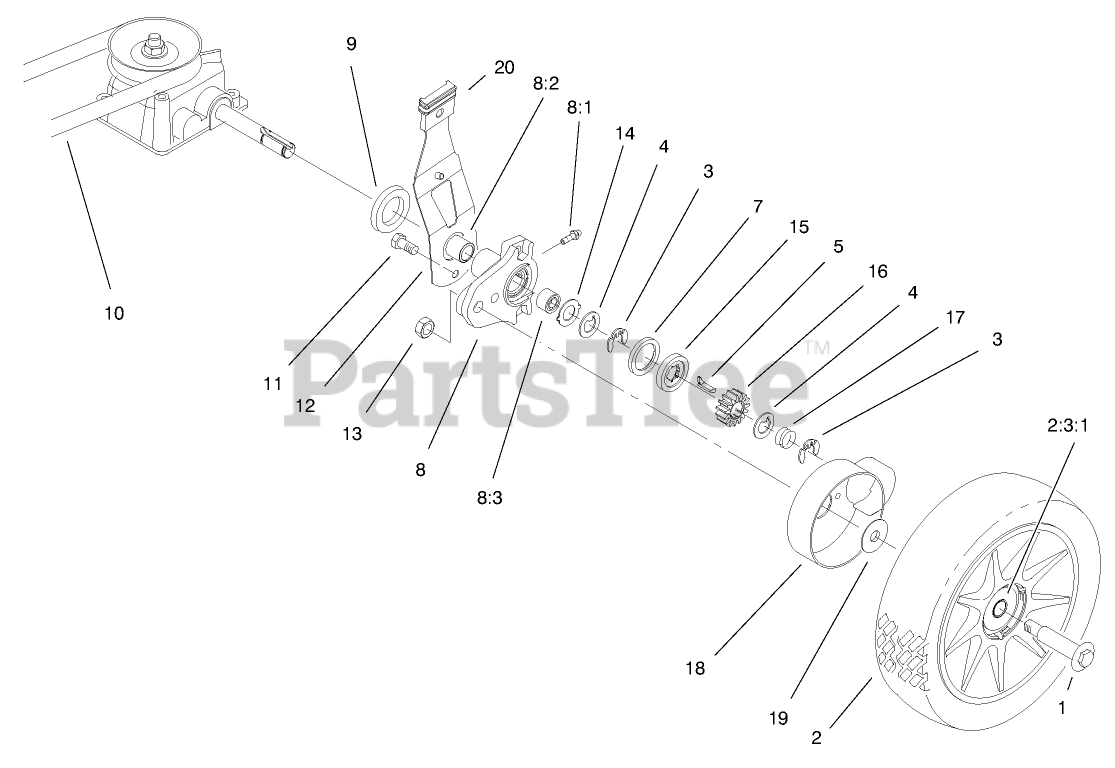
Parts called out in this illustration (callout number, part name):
1	BOLT-SHOULDER
2	WHEEL AND TIRE ASM
2:3	8" Wheel Tire ASM
2:3:1	BUSHING
3	RING-RETAINING,CLIP
4	WASHER-THRUST, KEYED
5	KEY-ROCKING, LH
6	KEY-ROCKING, RH
7	RING-FRICTION
8	REAR HEIGHT ADJUSTMENT ARM ASM
8:1	FITTING-GREASE
8:2	BUSHING
8:3	BUSHING
9	SPACER-SHAFT, AXLE
10	V-BELT
11	SCREW-HWH
12	REAR SPRING ARM ASM
13	NUT-JAM, LOCKING
14	WASHER-ARM, PIVOT
15	WASHER-CLUTCH
16	GEAR-PINION
17	SPRING-COMPRESSION
18	COVER-WHEEL
19	WASHER-STEPPED
20	KNOB-LEVER, HEIGHT ADJUSTMENT
